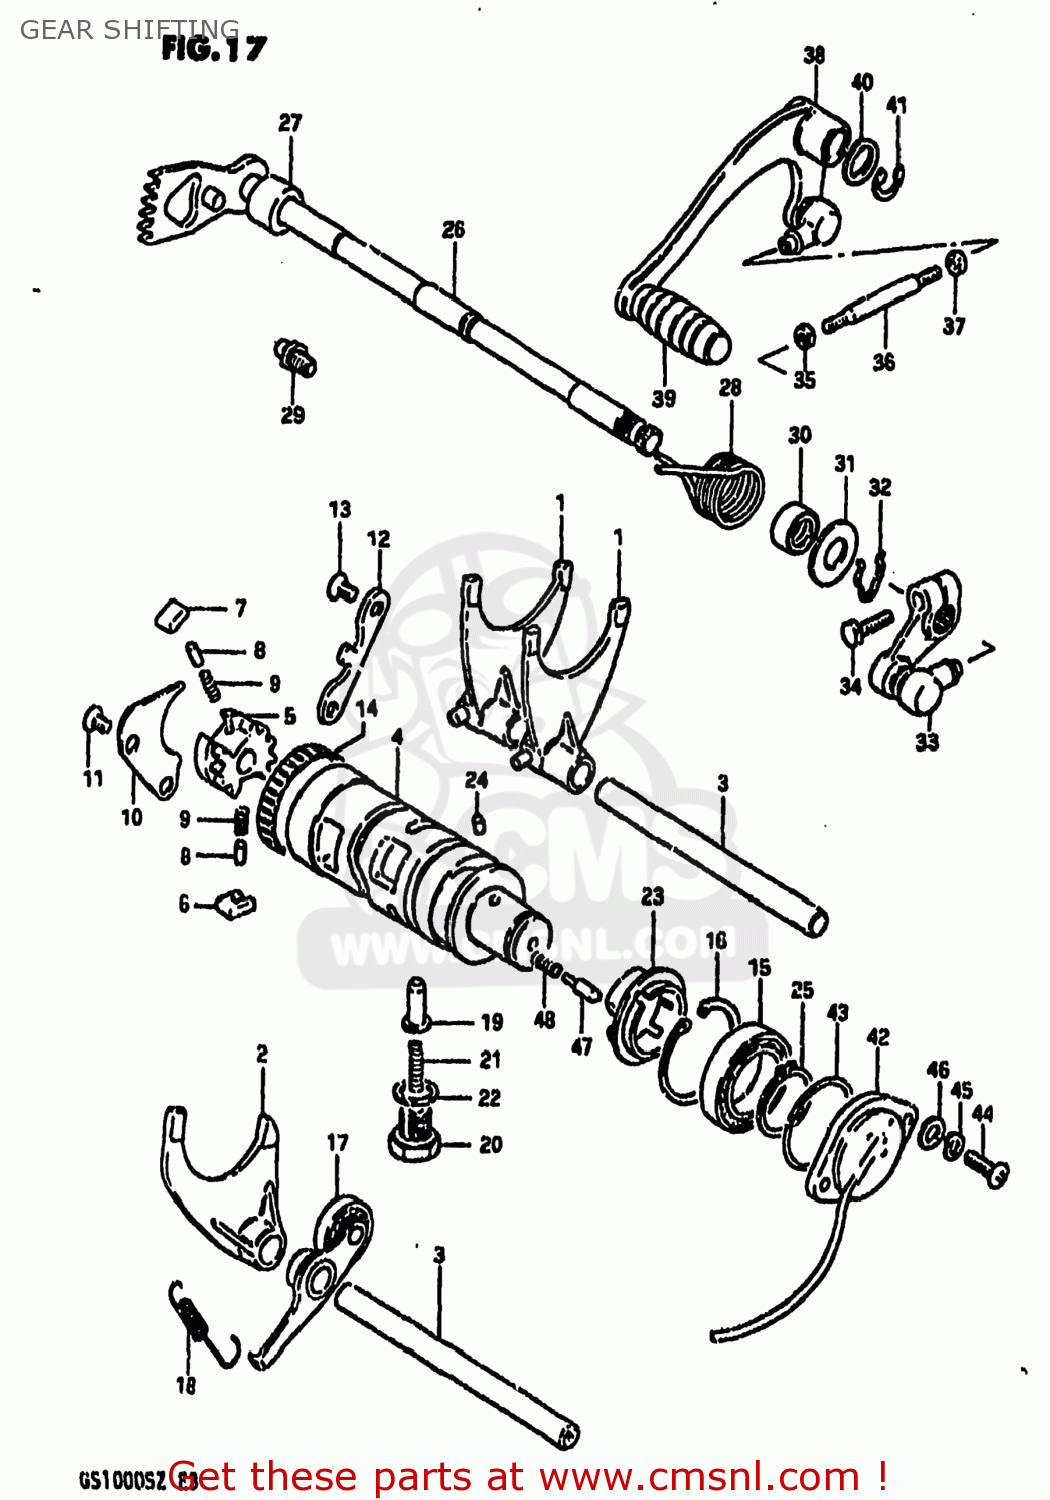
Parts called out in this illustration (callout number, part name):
1	FORK,GEAR SHIFT NO.1
2	FORK,GEAR SHIFT NO.2
3	SHAFT,GEAR SHIFT FORK
4	CAM,GEAR SHIFT
5	RETAINER,GEAR SHIFT CAM
6	PAWL,GEAR SHIFT NO.1
7	PAWL,GEAR SHIFT NO.2
8	PIN(5X8)
9	SPRING
10	LIFTER,GEAR SHIFT PAWL
11	SCREW
12	GUIDE,GEAR SHIFT CAM
13	SCREW
14	BEARING(43X49X12)
15	BALL BEARING
16	CIRCLIP
17	STOPPER,GEAR SHIFTING
18	SPRING
19	STOPPER,GEAR SHIFT CAM NO.2
20	HOLDER,GEAR SHIFT CAM STOP SPR
21	SPRING
22	GASKET(14X19.2X2) (NAS)
23	PLATE,GEAR SHIFT CAM STOPPER
24	PIN 4X6
25	CIRCLIP
26	SHAFT,GEAR SHIFT
27	SPACER(12X20X15.3)
28	SPRING
29	STOPPER,GEAR SHIFT CAM
30	OIL SEAL
31	WASHER (12.5X27X1.6)
32	SPRING,RETAINER
33	ARM,GEAR SHIFT LINK
34	BOLT
35	NUT
36	ROD,GEAR SHIFT LINK
37	NUT
38	LEVER ASSY,GEA
39	RUBBER,PEDAL
40	WASHER(12.5X20X1)
41	CIRCLIP
42	BODY, SHIFTING SWITCH
43	O RING(D:2.4,ID:36.5)
44	SCREW
45	LOCK WASHER
46	WASHER
47	PIN(5X15.5)
48	SPRING
